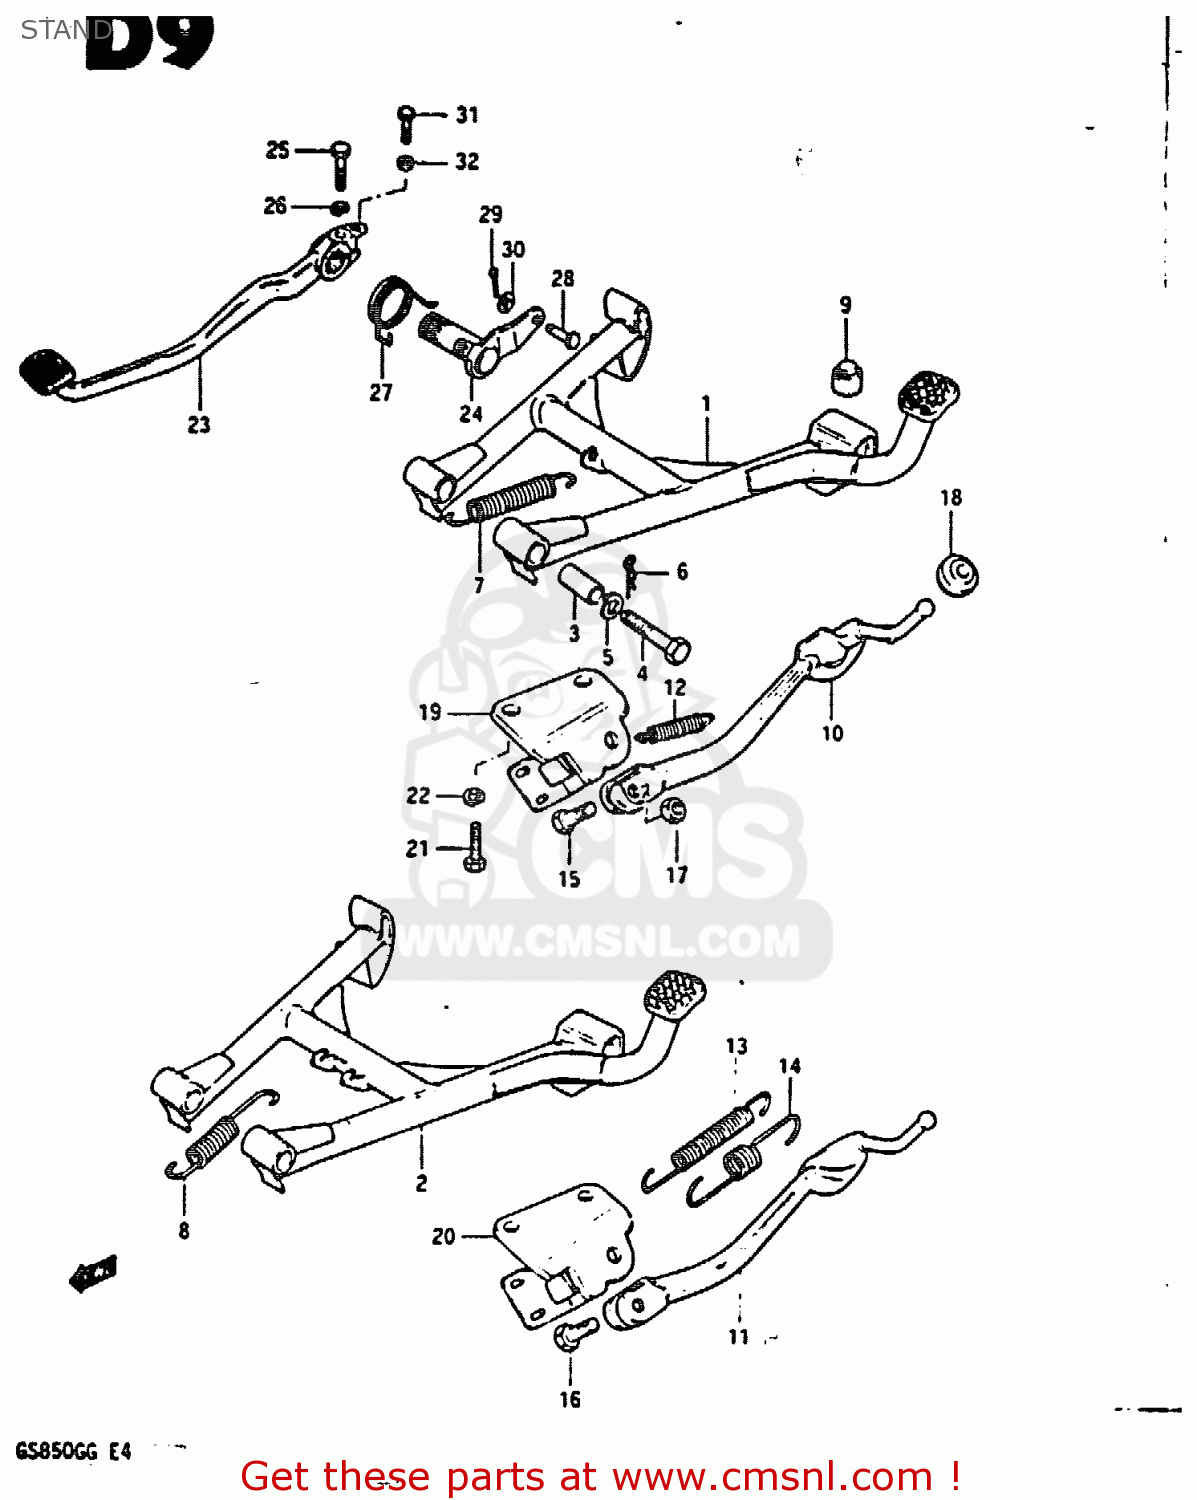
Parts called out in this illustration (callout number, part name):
1	STAND,CENTER
2	STAND, CENTER
3	SPACER(10X16X38.8)
4	BOLT
5	LOCK WASHER
6	CLIP
7	SPRING
8	SPRING
9	CUSHION
10	STAND,PROP
11	STAND, PROP
12	SPRING
13	SPRING
14	SPRING, OUTER
15	BOLT(10X30)
16	BOLT L:30
17	NUTM10X1.25X8
18	CUSHION
19	BRACKET,SIDE STAND
20	BRACKET
21	BOLT
22	LOCK WASHER
23	PEDAL,BRAKE
24	ARM,BRAKE PEDAL ROD
25	BOLT (8X30)
26	LOCK WASHER
27	SPRING
28	PIN
29	PIN
30	WASHER
31	BOLT
32	NUT 6MM
